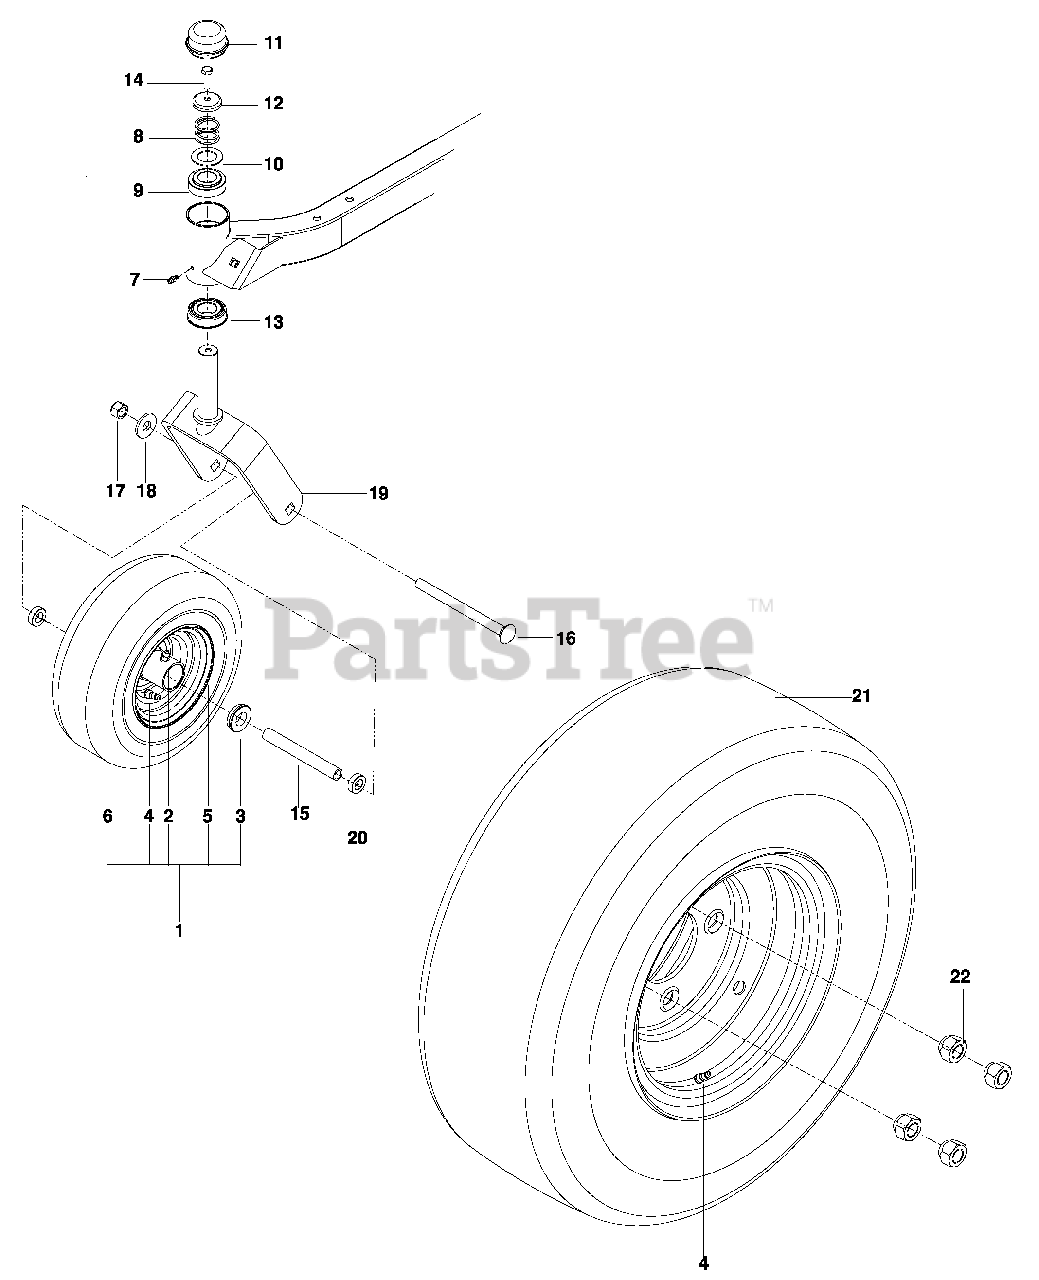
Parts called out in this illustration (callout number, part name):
1	CASTER TIRE ASSY
2	ZERK
3	BEARING, FLANGED
6	TIRE
7	ZERK
8	SPRING, CASTER
9	BUSHING, CASTER
11	CAP, GREASE
12	PLUG, CASTER
13	BEARING, FLANGED
14	HHB 5/16-18 x 1 NYLOC
16	BOLT, RD HD ½-13 x 6½
17	NUT ½ HEX NYLOC
18	WASHER ½ FLAT
19	YOKE, CASTER
20	SPACER 5/16
21	WHEEL ASSY REAR
22	NUT ½ LUG
